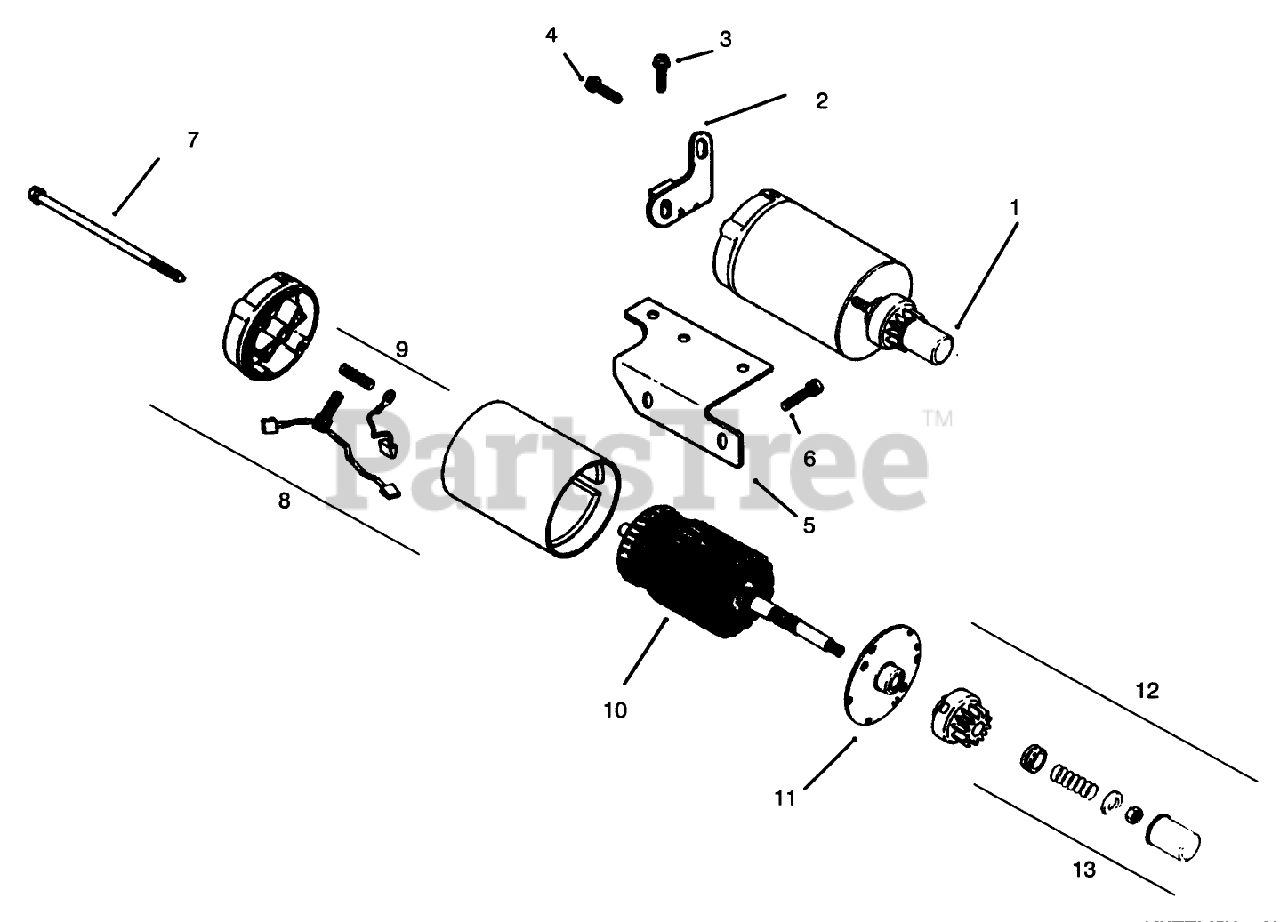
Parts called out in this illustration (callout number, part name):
1	Starter ASM INC 9-13
2	Brace-Starter Tail
3	Screw
4	Screw
5	Bracket-Solenoid
6	Screw
7	Bolt
8	End Cap ASM-INC 9
9	Kit-Brush
10	Armature
11	Cap-Drive End
12	Kit-Drive INC 13
13	Kit-Drive Parts
